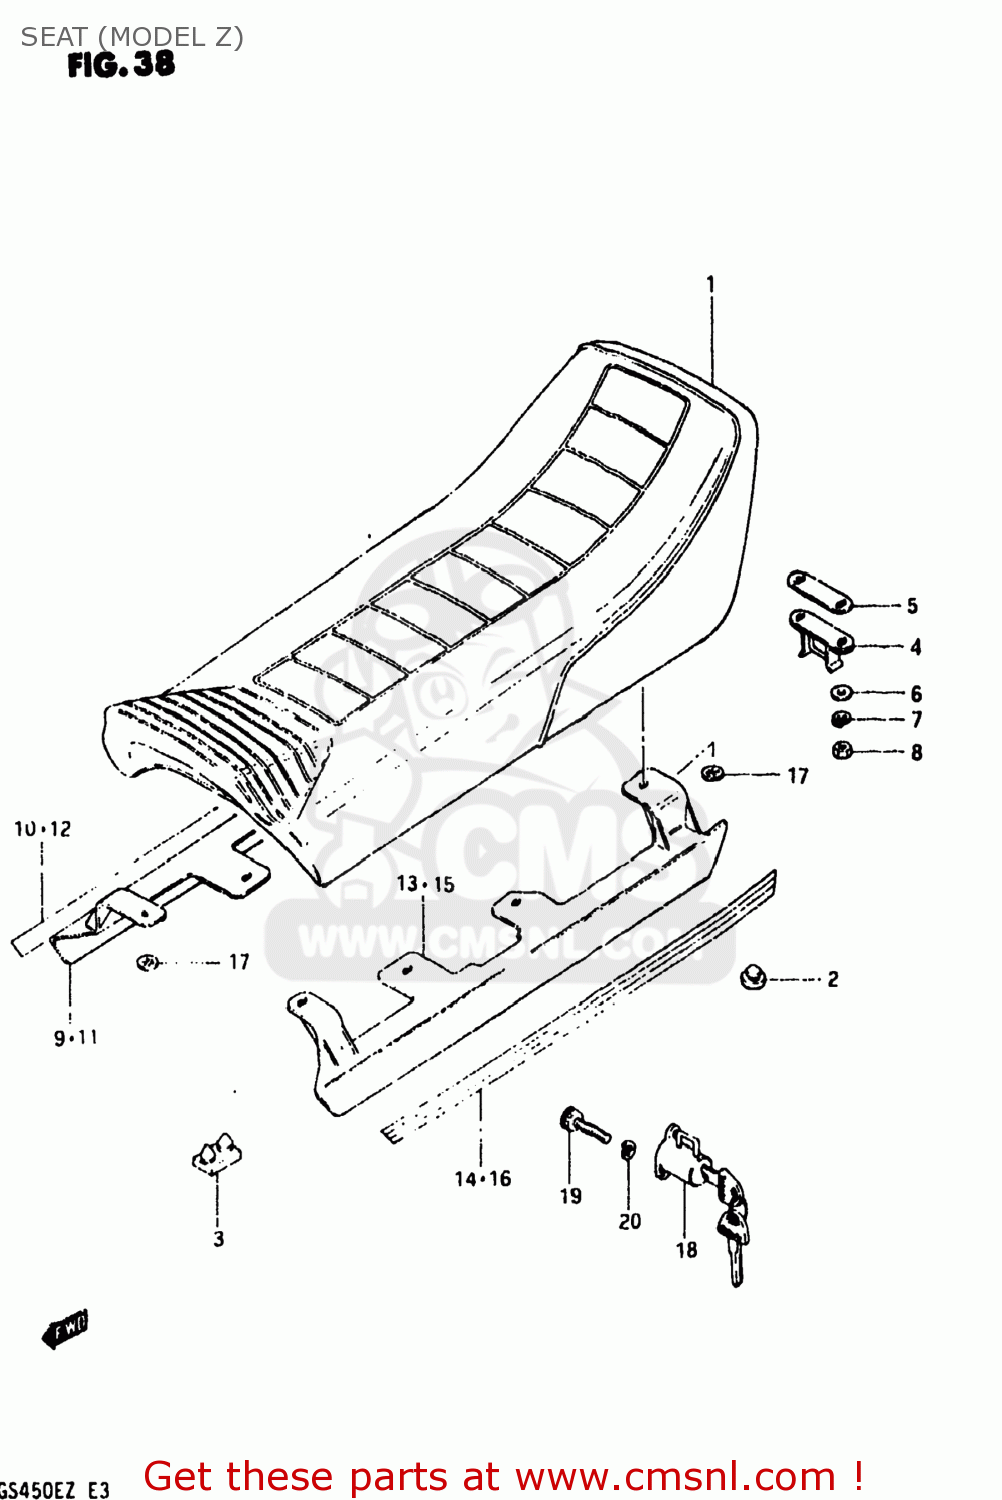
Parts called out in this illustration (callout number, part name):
1	SEAT ASSEMBLY
2	CUSHION
3	CUSHION
4	STRIKER,SEAT LOCK
5	SHIM,SEAT LOCK STRIKER
6	WASHER
7	LOCK WASHER
8	NUT 6MM
9	MOLDING,SEAT
10	TAPE,RIGHT
11	MOLDING,SEAT
12	TAPE,RIGHT
13	MOLDING,SEAT
14	TAPE,LEFT
15	MOLDING,SEAT
16	TAPE,LEFT
17	NUT
18	LOCK ASSEMBLY,HELMET
19	BOLT 6X11
20	LOCK WASHER
